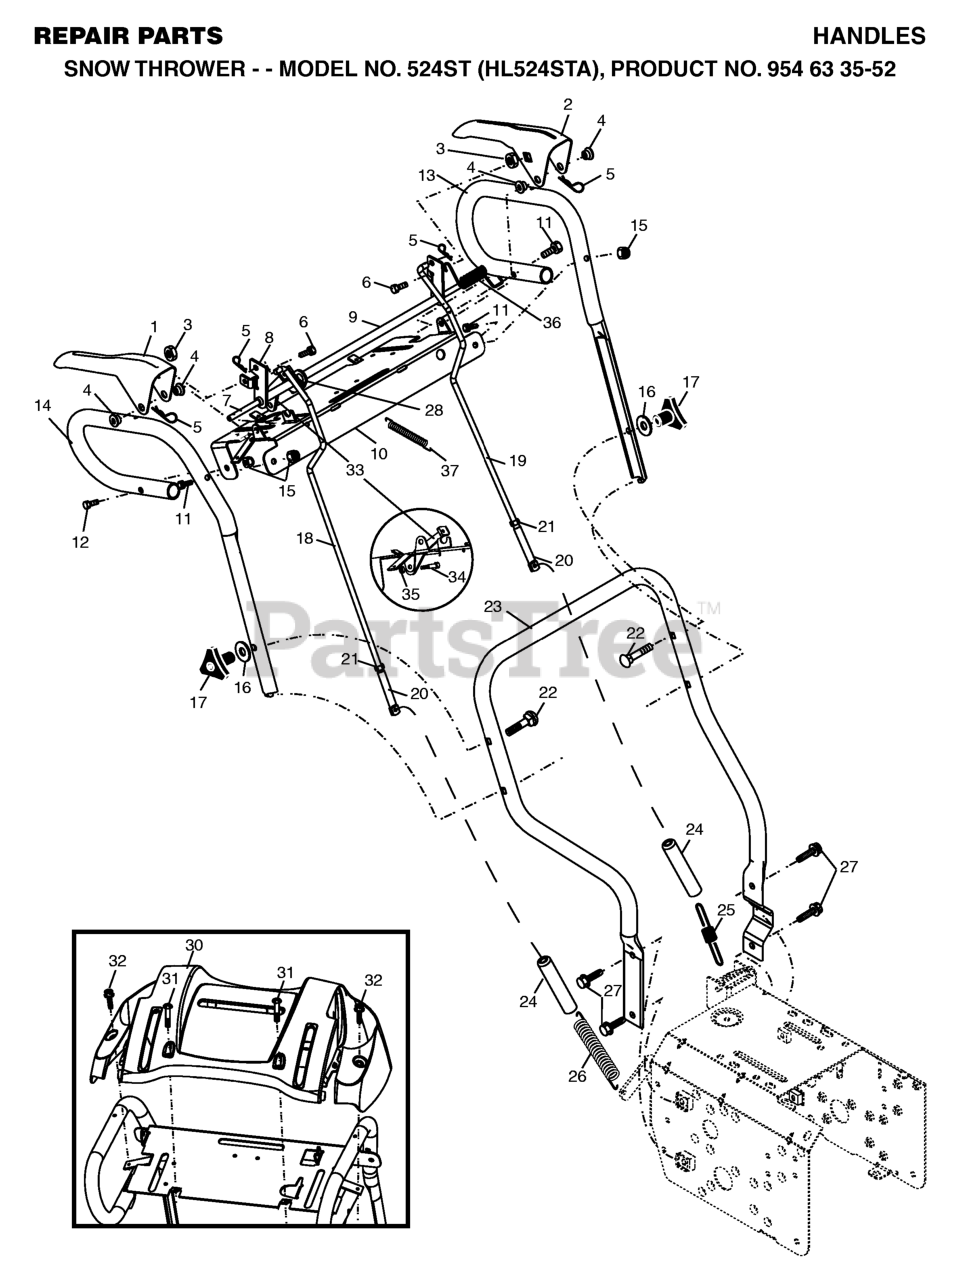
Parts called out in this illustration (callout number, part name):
1	LEVER, AUGER CONTROL
2	LEVER, TRACTION DRIVE CONTROL
3	NUT, CAGE 1/4-20
4	BUSHING, FLANGE
5	SPRING RETAINER
6	SCREW HEX HD 1/4-20 X 3/4
7	ROD.INTERLOCK
8	TUBE ASSM, INTERLOCK
9	TUBE.WELDMENT.INTERLOCK.LH
10	PANEL, CONTROL
11	HEX BOLT
13	HANDLE TUBE LH
14	HANDLE TUBE RH
15	NUT.71038.31-18.HEX.NYLOCK
16	WASHER
17	KNOB.HANDLE.3/8.TRI-POINT.BLAC
18	ROD.AUGER.CONTROL
19	ROD.TRACTION.CONTROL
20	ROD, END CONTROL
21	JAM NUT TI
22	BOLT 3/8-16 X 2-1/4
23	TUBE.LOWER.HANDLE.24.BLACK
24	SLEEVE, SPRING
25	SPRING, TRACTION DRIVE
26	SPRING, AUGER CONTROL
27	Capscrew, Hex Head, Flanged 3/8-16 x 1
28	PANEL CLIP
30	CONSOLE, HANDLE
31	SCREW, HEX HD TAPPING #10-24 1
32	SCREW, HEX HEAD, TAPPING
33	ARM.LATCH.INTERLOCK.YELLOW
34	BOLT, SHOULDER
35	NUT **
36	RP SPRING, TORSION
37	SPRING, INTERLOCK
